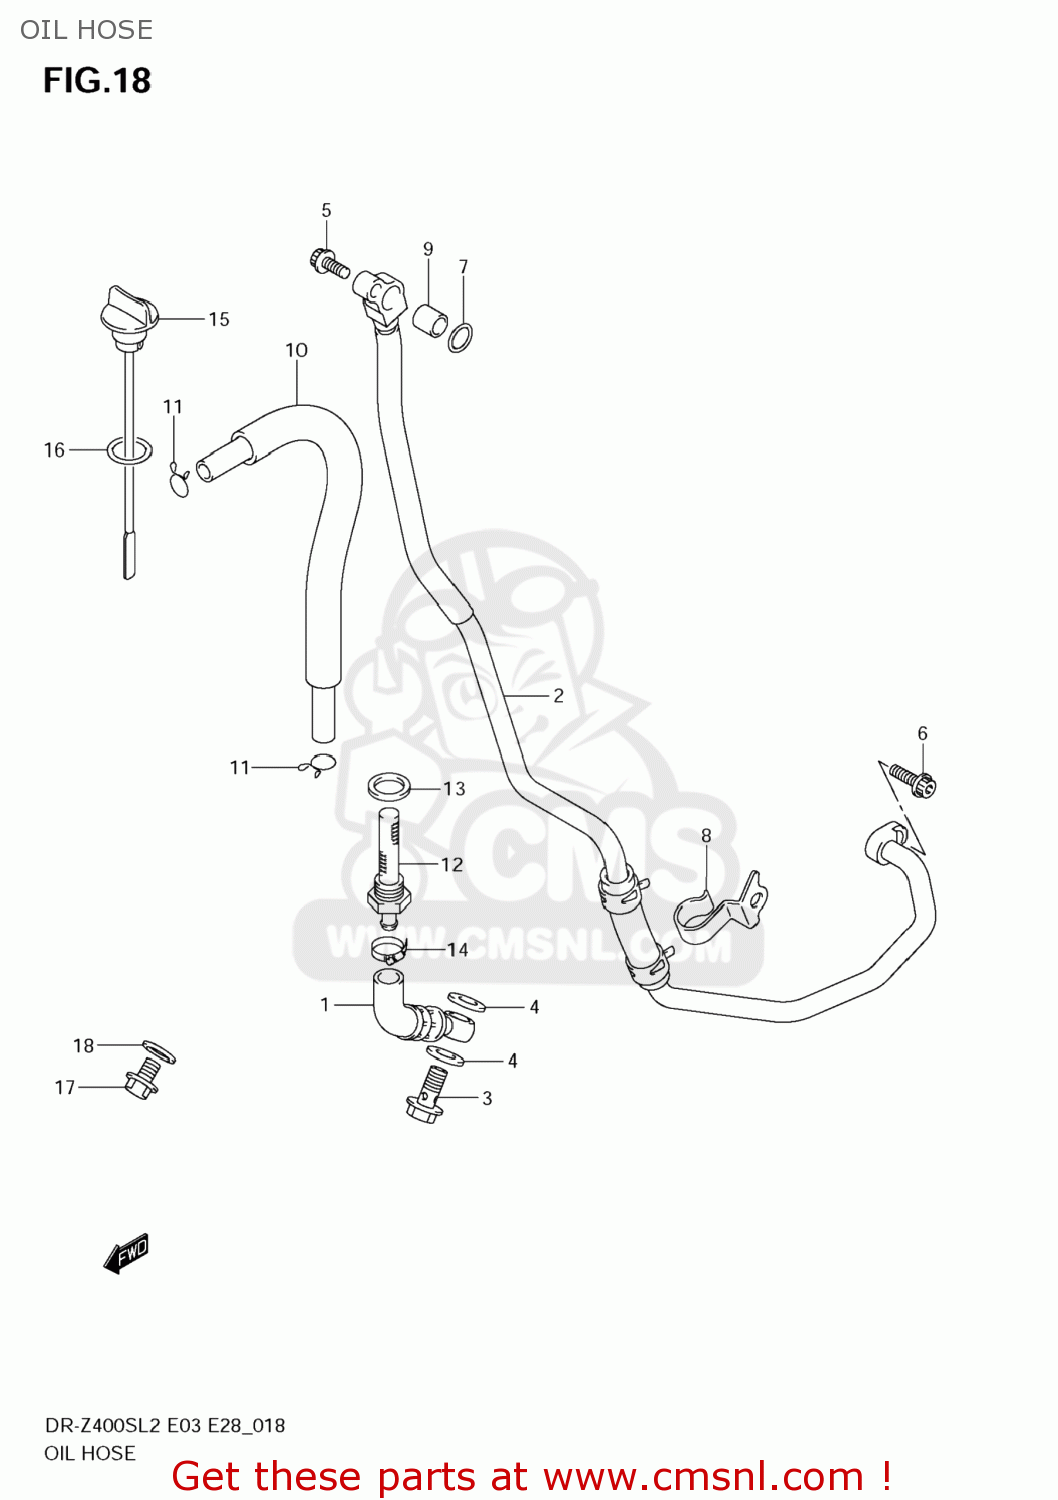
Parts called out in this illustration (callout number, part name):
1	HOSE,OIL TANK,R
2	HOSE,OIL TANK,L
3	BOLT UNION
4	GASKET(14X20X1.5) (NAS)
5	BOLT
6	BOLT
7	O RING(D:2.4,ID:11)
8	CLAMP,OIL TANK HOSE
9	PIN
10	HOSE,OIL TANK OVER FLOW
11	CLIP
12	STRAINER,FRAME HEAD UNDER
13	GASKET(18X22X2) (NAS)
14	CLAMP
15	GAUGE,OIL LEVEL
16	O RING(D:3.1,ID:16.8)
17	PLUG(10X12)
18	GASKET(10X14X3.6) (NAS)
